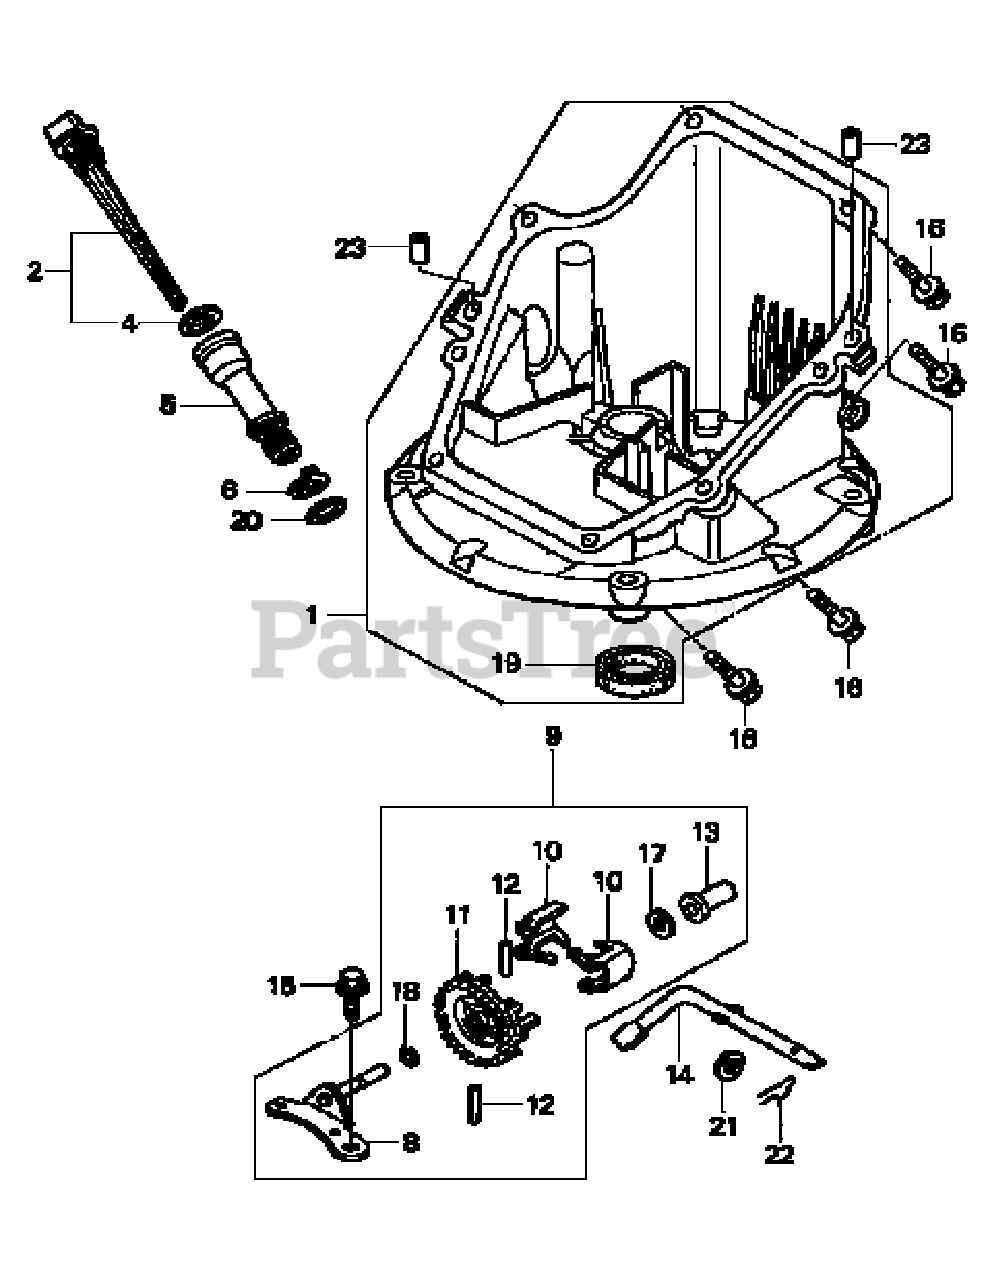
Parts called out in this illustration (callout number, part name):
1	Oil Pan Assy.
2	Oil Dipstick
4	Oil Filler Cap Gasket
5	Oil Filler Extension
6	Extension Lock Washer
8	Governor Holder Shaft
9	Governor Assy.
10	Governor Weight
11	Governor Weight Holder
12	Governor Weight Pin
13	Governor Slider
14	Governor Arm Shaft
15	Flange Bolt (6x14)
16	Flange Bolt (6x25)
17	Thrust Washer (6mm)
18	Governor Holder Clip
19	Oil Seal (28x41.25x6)
20	O-Ring (14.2x2.4)
21	Plain Washer (6mm)
22	Lock Pin (8mm)
23	Dowel Pin (8x20)
